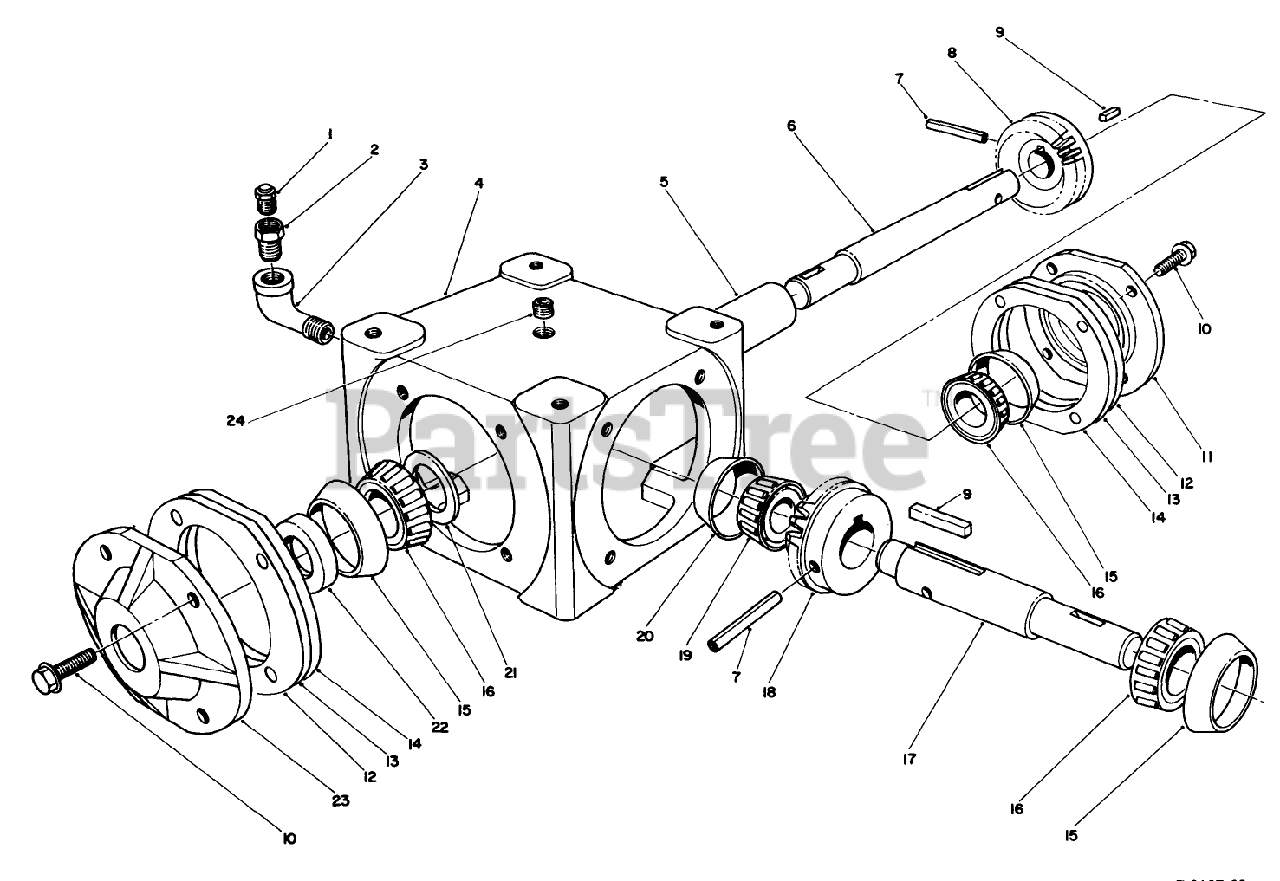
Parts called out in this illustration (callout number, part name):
1	Valve
2	BUSHING
3	Elbow-Street
4	HOUSING
5	SPACER
6	SHAFT
9	Key
10	SCREW-HH (OBS, C/R TO 3234-5)
12	GASKET
13	GASKET
14	GASKET
15	Cup
16	Cone
17	SHAFT
19	Cone
20	Bearing Cup
21	WASHER
22	Seal
24	PLUG (OBS, C/R TO 281-10)
